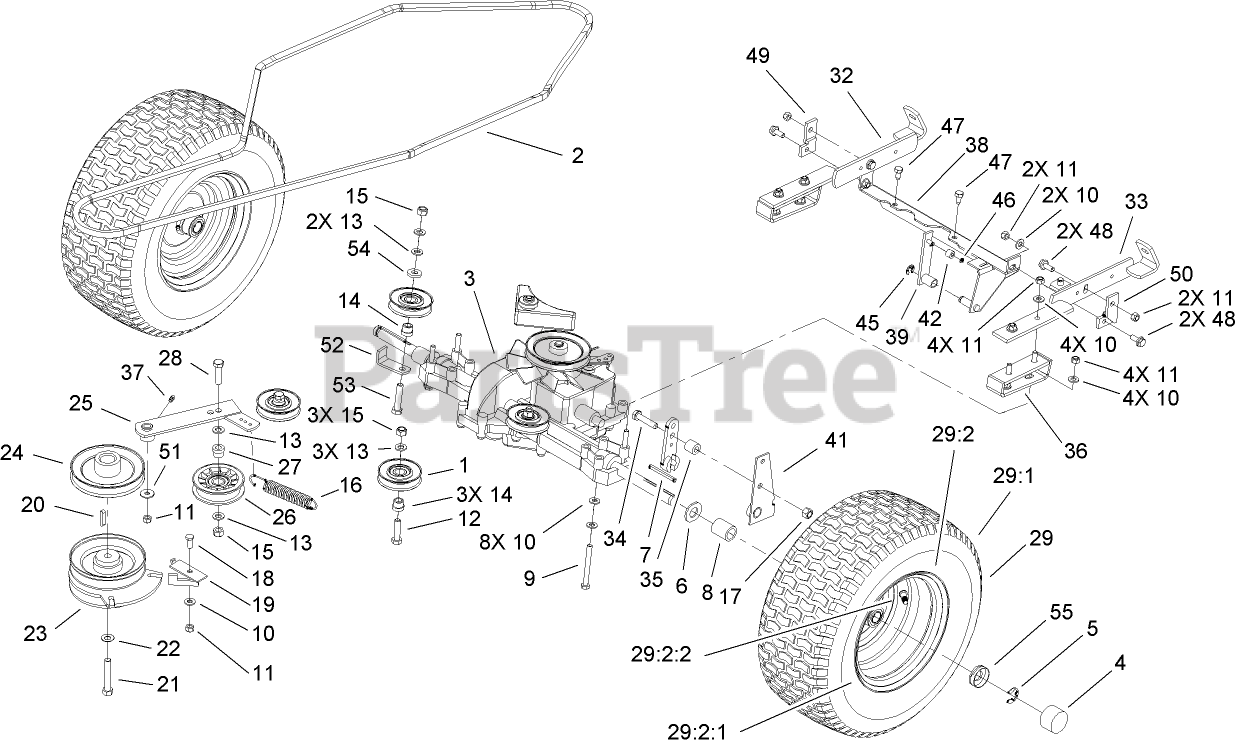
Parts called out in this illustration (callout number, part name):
1	PULLEY-IDLER
2	V-BELT-TRACTION
3	TRANSMISSION
4	CAP-HUB
5	CLIP-SPRING
6	WASHER
7	KEY-SQUARE
8	SPACER-AXLE
9	SCREW-HH
10	WASHER-PLAIN
11	NUT-LOCK, NI
12	SCREW-HH
13	WASHER-FLAT
14	BUSHING-IDLER
15	NUT-LOCK, NI
16	SPRING
17	NUT-LOCK, NI
18	SCREW-HH
19	RETAINER
20	KEY-SQUARE
21	SCREW-HH
22	WASHER-SPRING, BELLEVILLE
23	CLUTCH-ELECTRIC
24	PULLEY-ENGINE
25	ARM-IDLER
26	PULLEY-IDLER
27	BUSHING-IDLER
28	SCREW-HH
29	Wheel AND Tire ASM
29:1	TIRE
29:2	WHEEL ASM
29:2:1	Rim
29:2:2	Valve-Tire
32	Bracket-Right
33	Bracket-Left
34	SCREW-HH
35	SLEEVE
36	BRACKET-SUPPORT
37	FITTING-GREASE
38	Bar ASM
42	Roller
45	Stirrup
46	STIRRUP
47	SCREW-THREAD FORMING
48	SCREW-HEX
49	BRACKET-RIGHT
50	BRACKET-LEFT
51	WASHER-PLAIN
52	RETAINER-BELT
53	SCREW-HH
54	WASHER-FLAT
55	RETAINER-CAP, HUB
